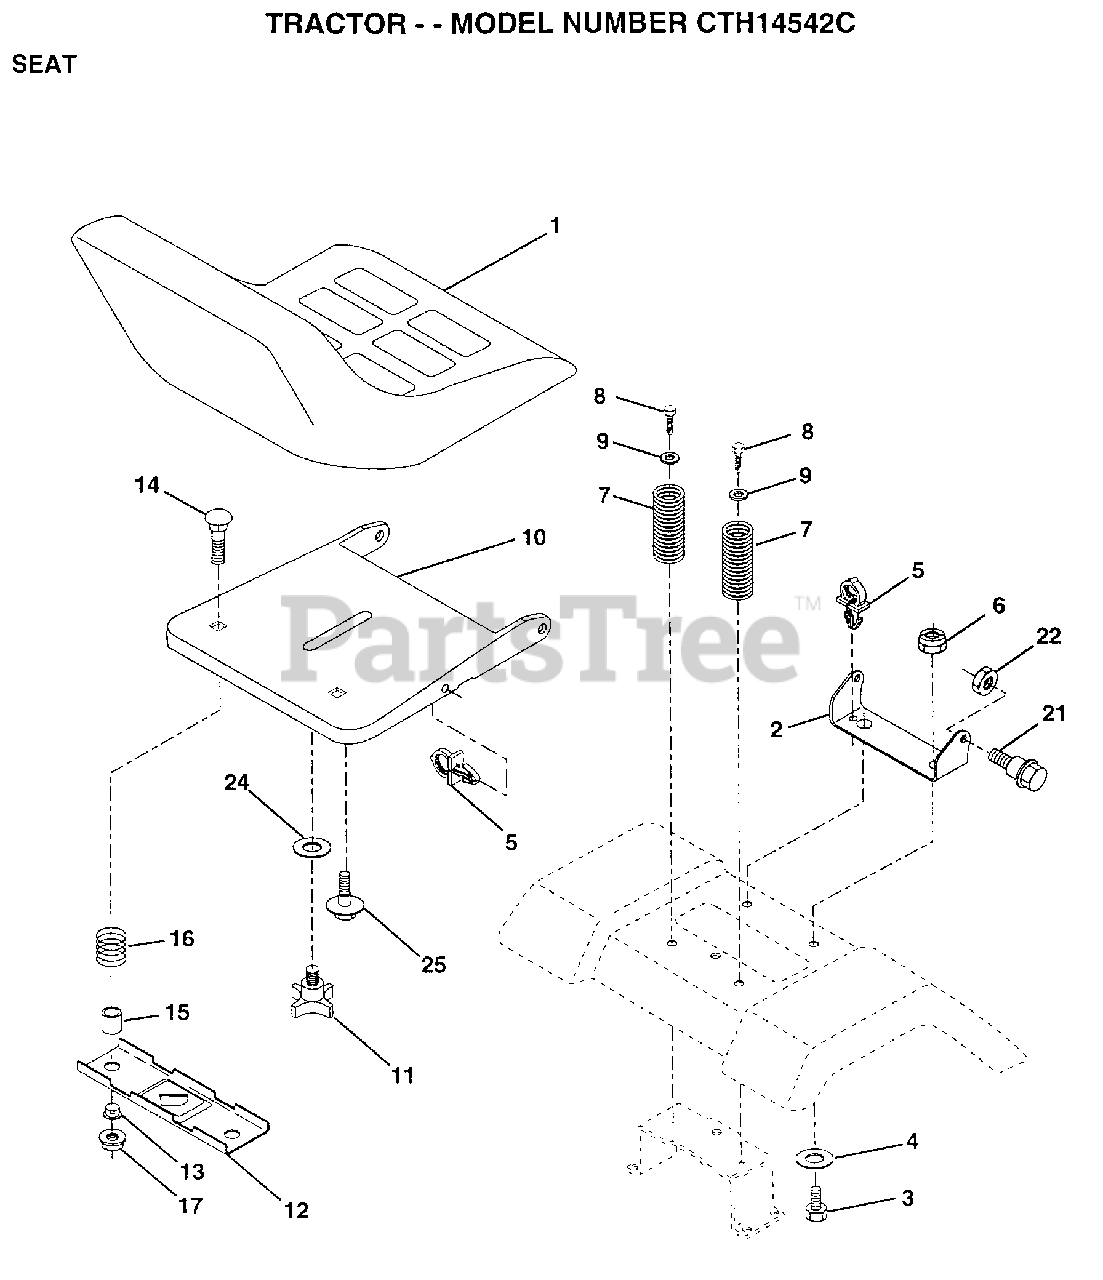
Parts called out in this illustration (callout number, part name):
2	BRACKET PVT SEAT
3	BOLT
4	WASHER PM
5	CLIP.PUSH-IN.HING
6	NUT
7	SPRING COMPRESSIO
8	SCREW GTV
9	WASHER
11	"KNOB 1/2"" YT"
12	BRKT SWITCH
13	BUSHING
15	SPACER SPLIT
16	SPRING COMPRESSED
21	"BOLT,SHOULDER"
24	WASHER
25	"BOLT,SHOULDER"
